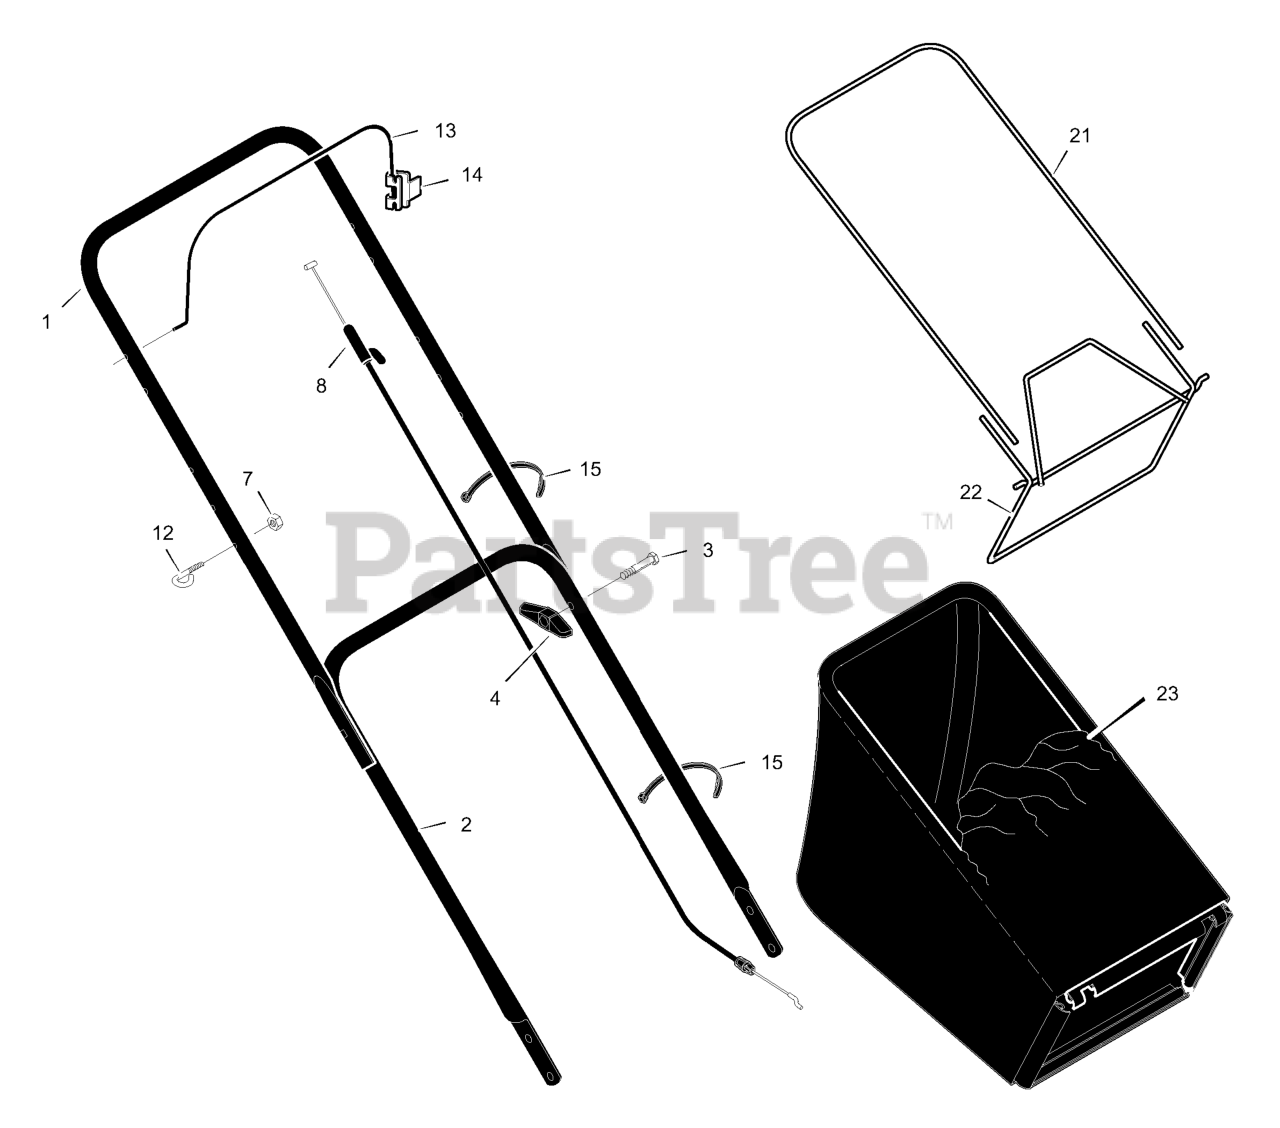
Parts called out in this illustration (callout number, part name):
1	Handle, Upper
2	Handle, Lower
4	Knob, Plastic
7	Locknut
8	Engine Stop Cable
12	Guide, Rope
13	Engine Stop Lever
14	Bracket, Stop Lever
15	Fastener, Cable
21	Frame, Top
22	Frame Assembly
23	Bag, Cloth
